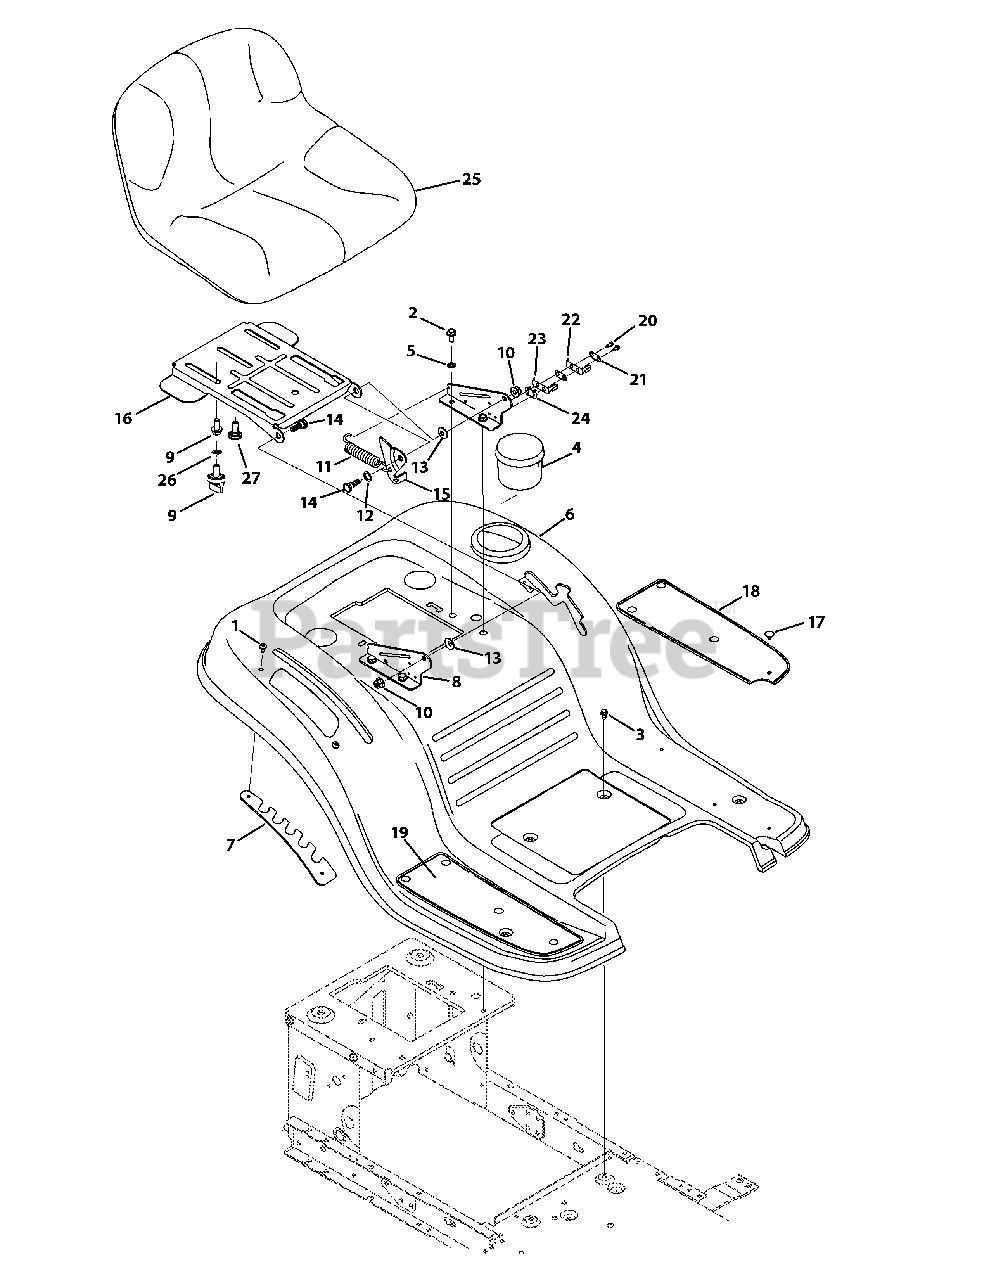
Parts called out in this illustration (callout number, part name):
1	Screw, 1/4-20 x .500
2	Screw, 5/16-18 x .750
3	Screw Pan Torx Head, 1/4-20 x .500
5	Loack Washer, 5/16
6	Fender
7	Lift Adjuster Bracket
8	Seat Mount Bracket
9	Hex Flange, 3/8-16 x .875
10	Flangelock Nut, 5/16-18
11	Extension Spring
12	Flat Washer, .510x .750 x .033
13	Bell Washer, .340 x .872 x .060
14	Shoulder Screw, 5/16-18 x .437 x .268
15	Lift Seat Bracket
16	Pivot Seat Manual Adjust Bracket
17	Ratchet Clip, .250 x .500
18	Foot Pad, LH
18	Foot Pad, Abrasive, LH
19	Foot Pad, RH
19	Foot Pad, Abrasive, RH
20	Screw, 8-18 x .500
21	Insulator Plate
22	Outer Seat SPring
23	Inner Seat Spring
24	Insulator Boss Plate
25	High Back Seat, Troy-Bilt
26	Lock Washer
27	Screw, Shldr., .625 x .145 x 3/8-16†
